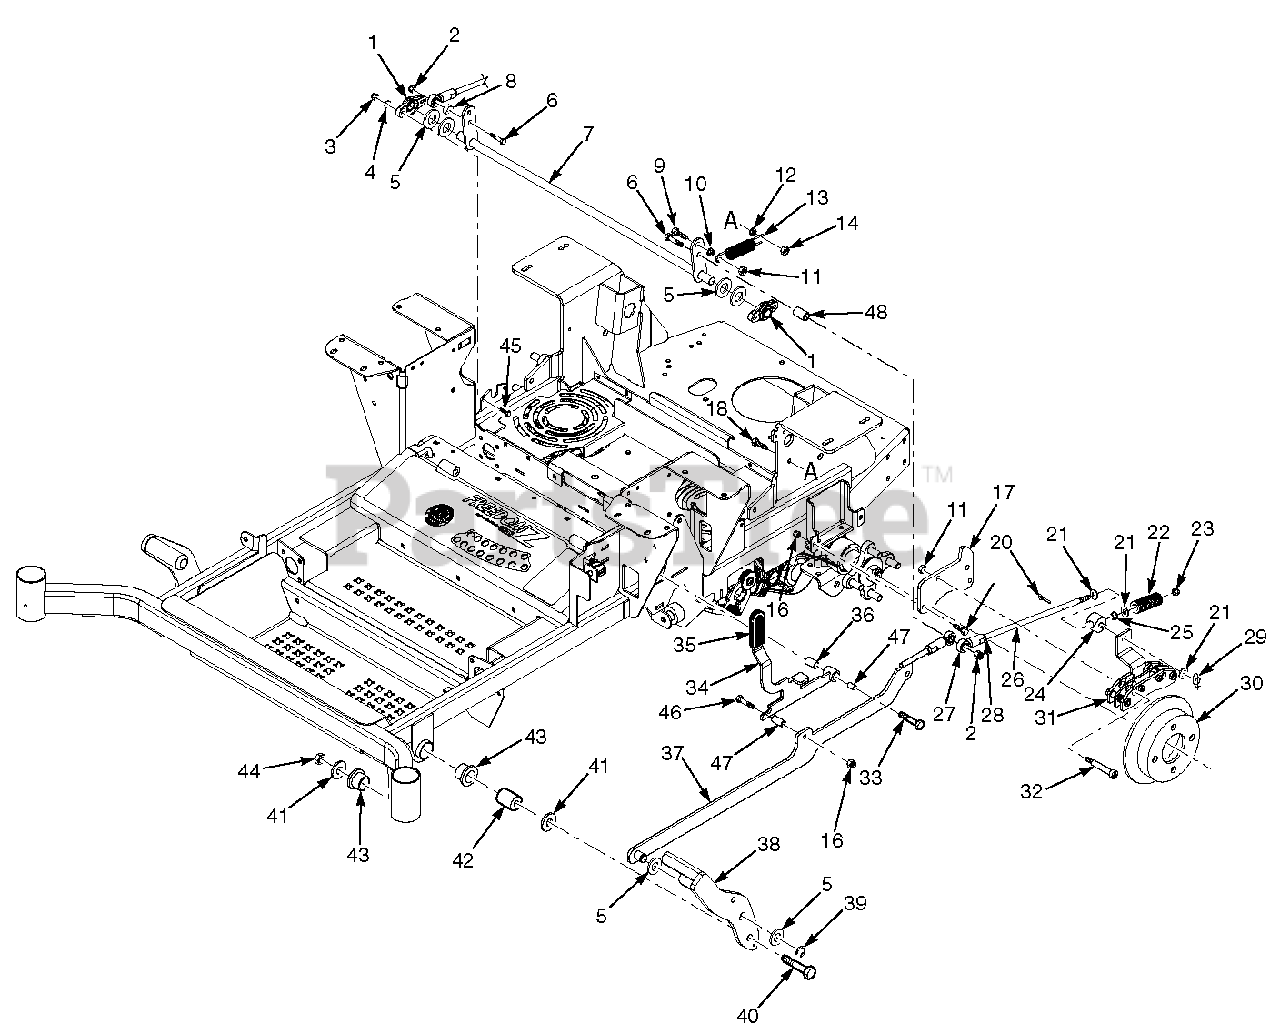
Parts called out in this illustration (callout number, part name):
1	Bearing
2	Nut, Elastic Stop 3/8-16
3	Nut, Elastic Stop 1/4-20
4	Flatwasher, 1/4-.312 x .750 x .065
5	Flatwasher, 5/8-.656 x 1.312 x .095
6	Bolt, Hex Head 3/8-16 x 2-1/4"
7	Weldment, Brake Lever
8	Spacer
9	Bolt, Hex Head 3/8-16 x 1-1/4"
10	Nut, Serrated Flange 3/8-16
11	Nut, Center Lock 3/8-16
12	Nut, Serrated Flange 5/16-18
13	Spring
14	Nut, Center Lock 5/16-18
15	Flatwasher, 3/8-.391 x .938 x .105
16	Nut, Elastic Stop 5/16-18
17	Mounting Bracket, Brake
18	Bolt, Hex Head 5/16-18 x 1-1/4"
19	Bolt, Hex Head 5/16-18 x 1"
20	Cotter Pin, 3/32 x 3/4"
21	Flatwasher, 3/8-.406 x .812 x .065
22	Spring, Brake
23	Nut, Elastic Stop 3/8-24
24	Swivel Assembly, Brake
25	Bearing
26	Link, Brake
27	Rod End
28	Nut, 3/8-24 UNF Jam
29	Pin, Rue Cotter - 3/8" Dia.
30	Brake Hub
31	Brake Caliper
32	Bolt, Shoulder 1/2 x 2-1/2"
33	Bolt, Shoulder 1/2 x 2"
34	Latch Assembly, Brake
35	Grip, Brake Lever
36	Bearing
37	Linkage Weldment Assembly, Brake
38	Brake Pedal Weldment
39	Retaining Ring, .625 Ext. "E"
40	Bolt, Hex Head 1/2-13 x 3"
41	Flatwasher, 1/2-.562 x 1.375 x .109
42	Sleeve
43	Bearing
44	Nut, Center Lock 1/2-13
45	Bolt, Hex Head 1/4-20 x 1"
46	Bolt, Hex Head 5/16-18 x 1-3/4"
47	Sleeve, Handle Pivot
48	Spacer
